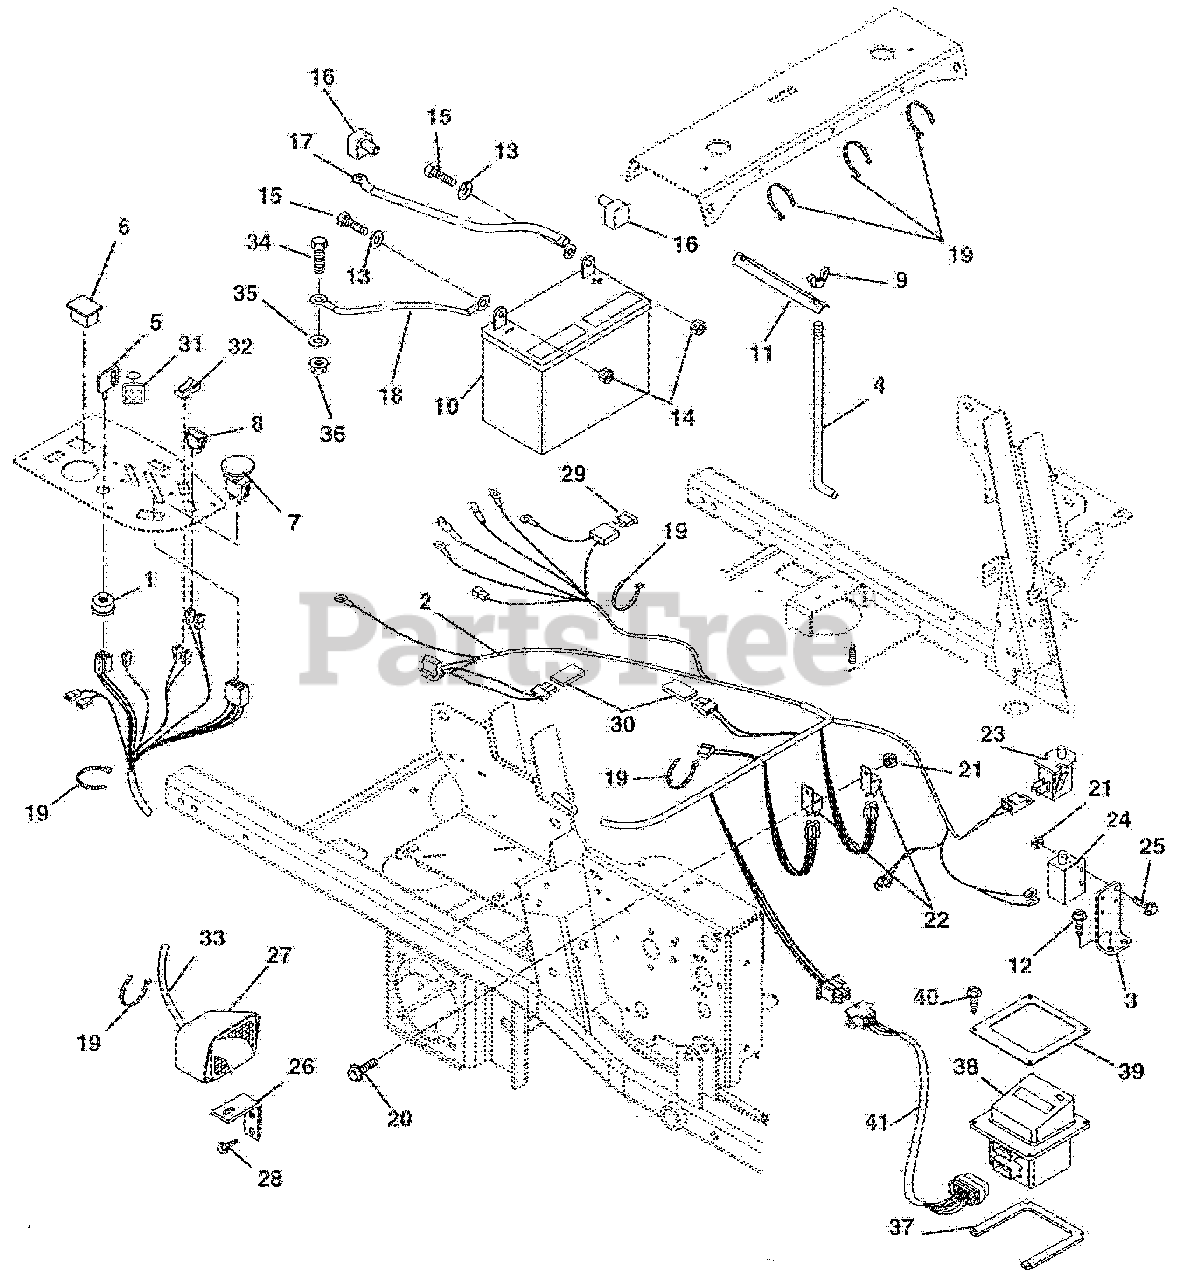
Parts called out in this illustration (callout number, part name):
1	Switch, Ignition
2	Harness, Z-6 Pin Wiring (EYE-Q) (066, 067, 068, 070, 071, 072)
3	Mount, Safety Switch
4	Rod, Battery Holddown .25 x 6.62
5	Key, with Shield
7	Switch, PTO Clutch
8	Light-Indicator Kit (066, 067, 068, 070, 071, 072)
9	Nut-Locking Wing .25-20
11	Hold Down
12	Screw-Tapping .25-20 x .50 Hex Washer Head
13	Washer-Flat-Steel .281 x .620 x .065
14	Nut-Locking-Top-Flange .25-20
15	Bolt-Hex .25-20 x .75 Grade 5
16	Battery Terminal Boot, Red
17	Starter Cable 13 in.
18	Ground Cable
19	Cable Tie
20	Screw-Machine 10-24 x .50 Hex Washer Head
21	Nut-Locking-Nylon 10-24 With Insert
22	Relay (Included with Harness)
23	Switch-Snap Mounting
24	Switch-Single Pole
25	Screw-Machine 10-24 x .75 Hex Washer Head
26	Bracket, Headlight Mounting Left
27	Headlight
28	Screw-Tapping .38-16 x .50 Hex Washer Head
29	Fuse, 30 Amp (Included with Harness)
30	Diode, Connector Shell
31	Key Chain
32	Switch, Light
33	Harness, Headlight Kit
34	Bolt-Hex .31-18 x .75 Grade 5
35	Washer-Flat-Steel .344 x .688 x .065
36	Nut-Locking-Top-Flange .31-18
37	Spacer, Enclosure Mounting (Bottom)
38	Assembly, Eye-Q
39	Plate, Eye-Q Stiffener (Top)
40	Screw, Machine 10-24 x 1.00
41	Harness, Eye-Q
